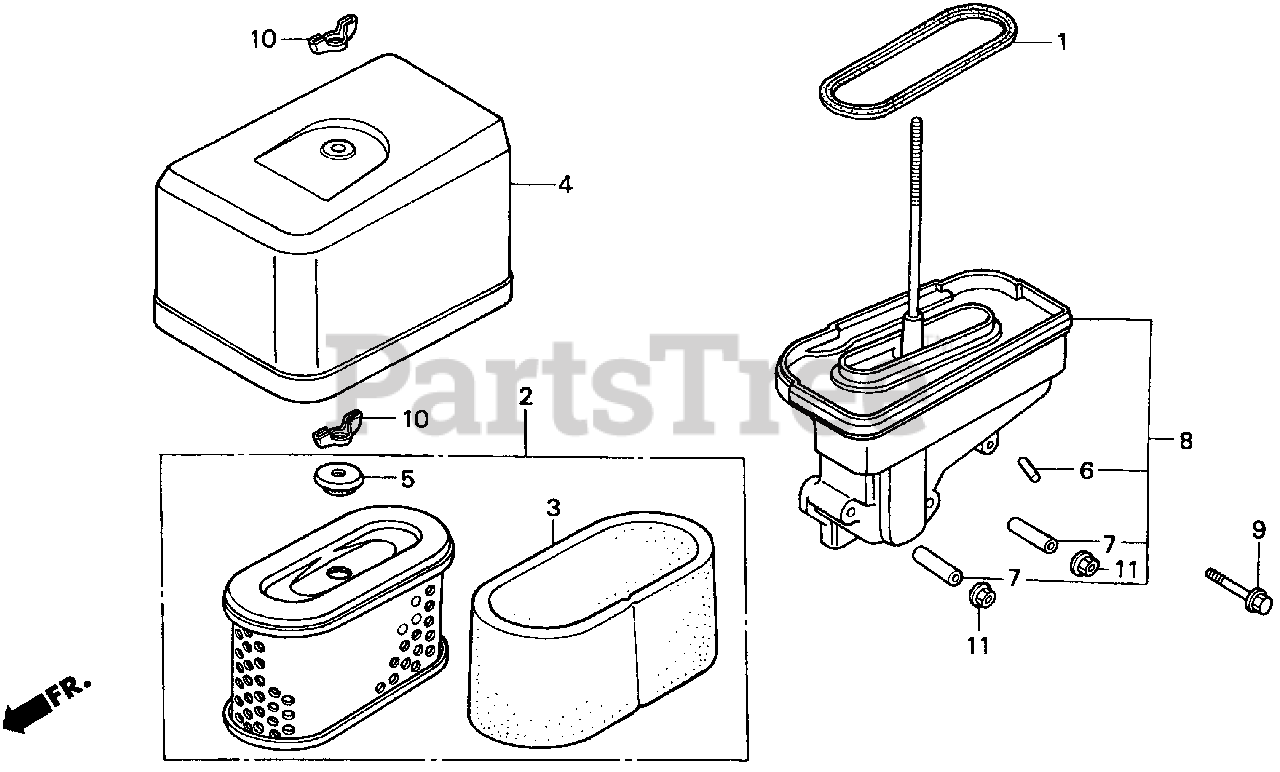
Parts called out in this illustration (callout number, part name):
1	GASKET, ELBOW
2	ELEMENT COMP., AIR CLEANER (METAL BASE)
2	ELEMENT, AIR CLEANER (METAL BASE)
3	FILTER (OUTER)
4	COVER, AIR CLEANER (DUAL)
5	GROMMET, AIR CLEANER
6	COLLAR, AIR CLEANER
7	COLLAR, AIR CLEANER
8	ELBOW COMP., AIR CLEANER
9	BOLT, FLANGE (6X35)
10	WINGNUT, TOOL BOX SETTING
11	NUT, FLANGE (6MM)
